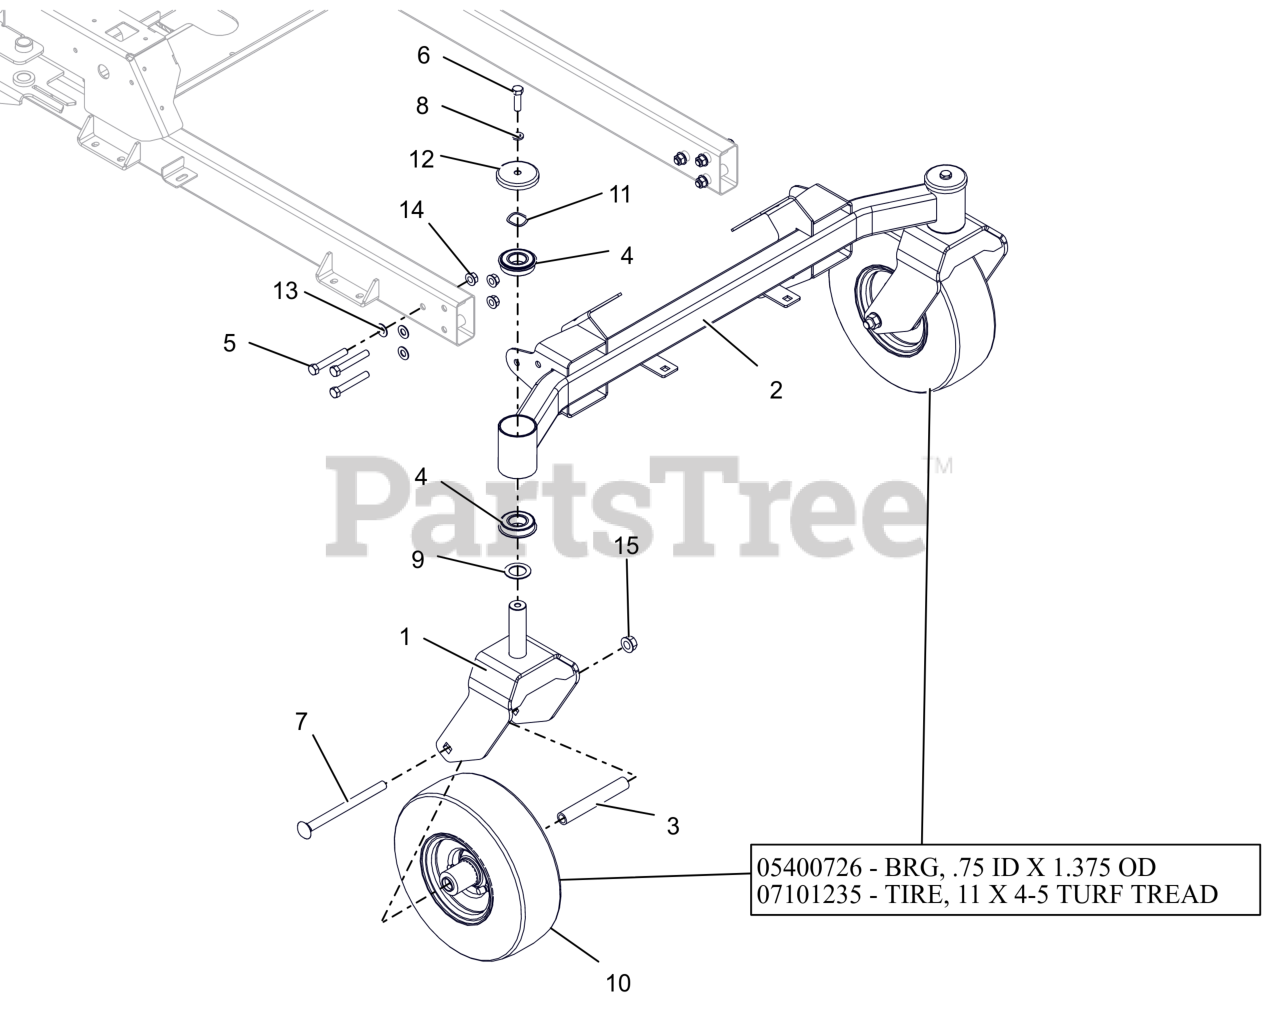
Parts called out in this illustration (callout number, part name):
1	WMT-CASTER FORK-X
2	WMT-FRONT AXLE-X/XL
3	SPACER, ROLLED WHEEL
4	BEARING, BALL -2.000 OD X 1.000 ID X .5625 W/RING
5	BLT, HEX .38-16X2.50 G8 ZCC
6	BLT, HEX .38-16X1.25 G5 ZCC
7	BLT, RHSN .50-13X6.50 G5 ZCC
8	WSHR,LK-REG .375X.094 ZCC
9	WSHR-HRD-THRS 1.007X1.542X.062
10	ASM, WHL/TIRE 11X4.00-5
10	BRG, .75 ID X 1.375 OD
10	TIRE, 11X4-5 TURF TREAD
10	TUBE 11 X4.0-5
11	WSHR-WAVE 1.0X1.25X.028 .145FH
12	SHIELD, AXLE BEARING
13	WSHR,FLT-HRD.406X.812X.055 MZC
14	NUT-LK-TOP-FLG .375-16 GG ZCC
15	NUT-LK-TOP-FLG .500-13 GF ZCC
